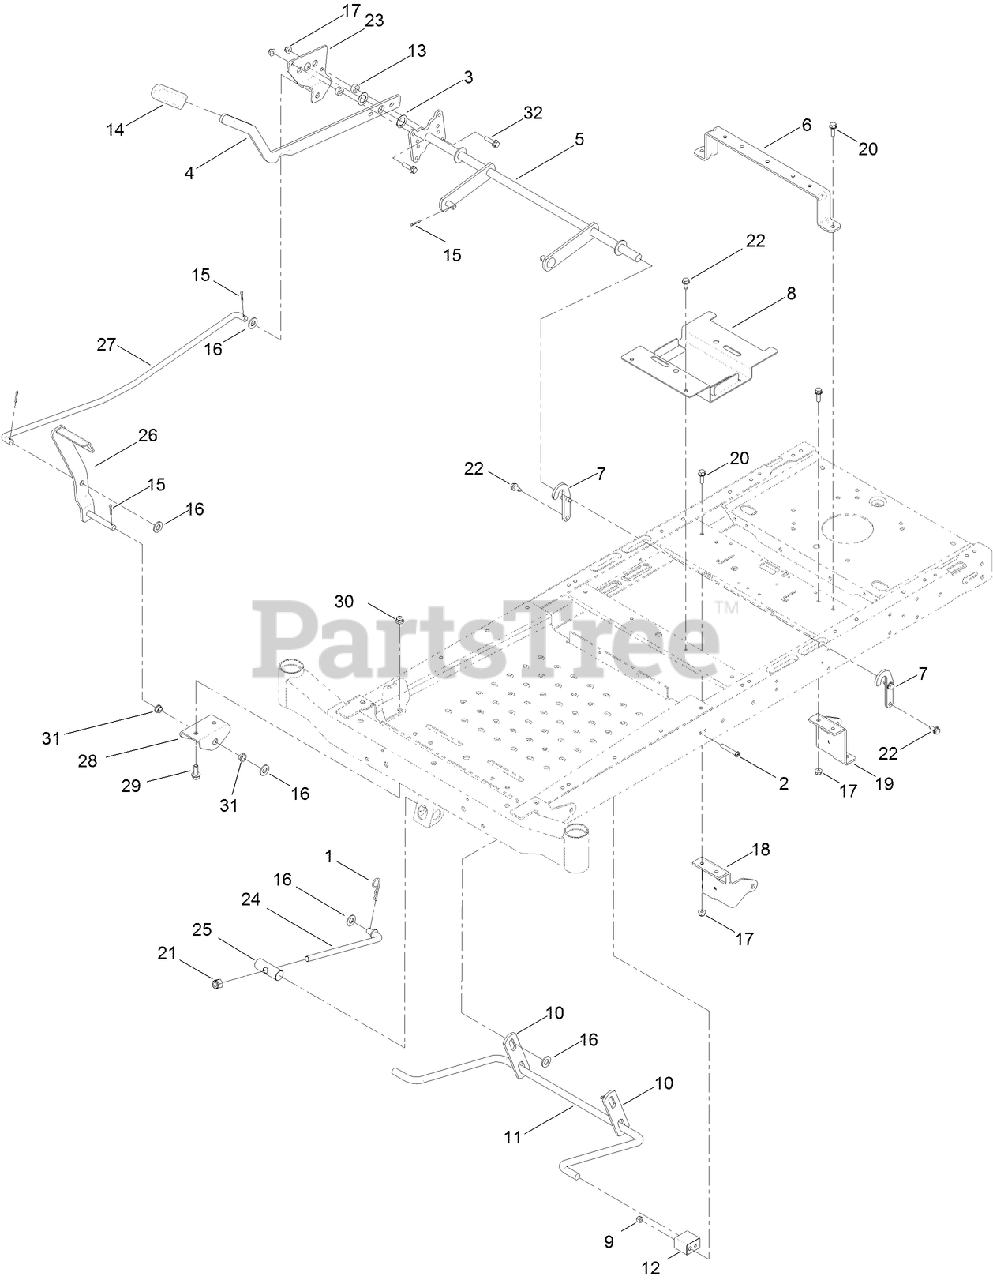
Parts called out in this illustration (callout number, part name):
1	PIN-COTTER
2	SCREW-HSBH
3	WASHER-THRUST
4	LEVER-LIFT
6	BRACE-SEAT, REAR
7	BRACKET-LIFT
8	BRACKET-BATTERY
9	NUT-LOCK, NI
10	LINK-LIFT
11	ARM-LIFT, REAR (WIDE)
12	BLOCK-PIVOT
13	SPACER
14	GRIP-LEVER
15	PIN-COTTER
16	WASHER-FLAT
17	NUT-HF, NI
18	MOUNT-HYDRO, FRONT (RH)
20	SCREW-HHF
21	NUT-HEX
22	SCREW-HWHTF
23	PLATE-FOOTLIFT
25	PIN-PIVOT
27	ROD-FOOTLIFT
28	BRACKET-FOOTLIFT
29	SCREW-HHF
30	NUT-HF, NI
31	BUSHING-FLANGE
32	SCREW-HHF
